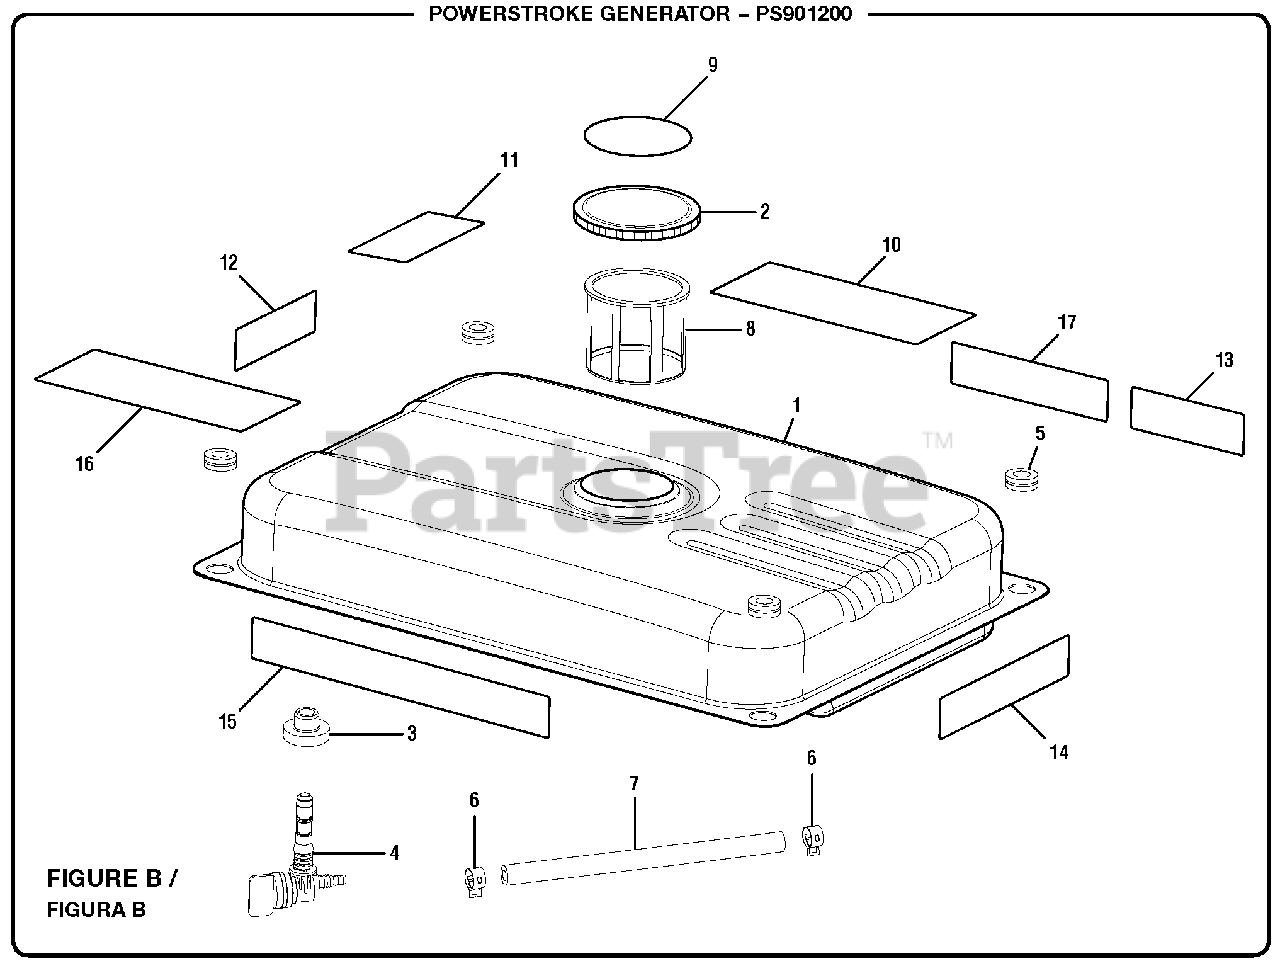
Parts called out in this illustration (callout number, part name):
3	Fuel Tank Bushing
4	Fuel Valve w/Filter
5	Fuel Tank Isolator
6	Fuel Hose Clamp (D7)
7	Fuel Hose
8	Fuel Filter
9	Fuel Stabilizer Label
10	Danger Label
11	E-85 Label
12	Starting Label
13	Combustion Label
14	Ground Warning Label
15	Logo Label
16	CPSC Label
17	Inquiries Label
